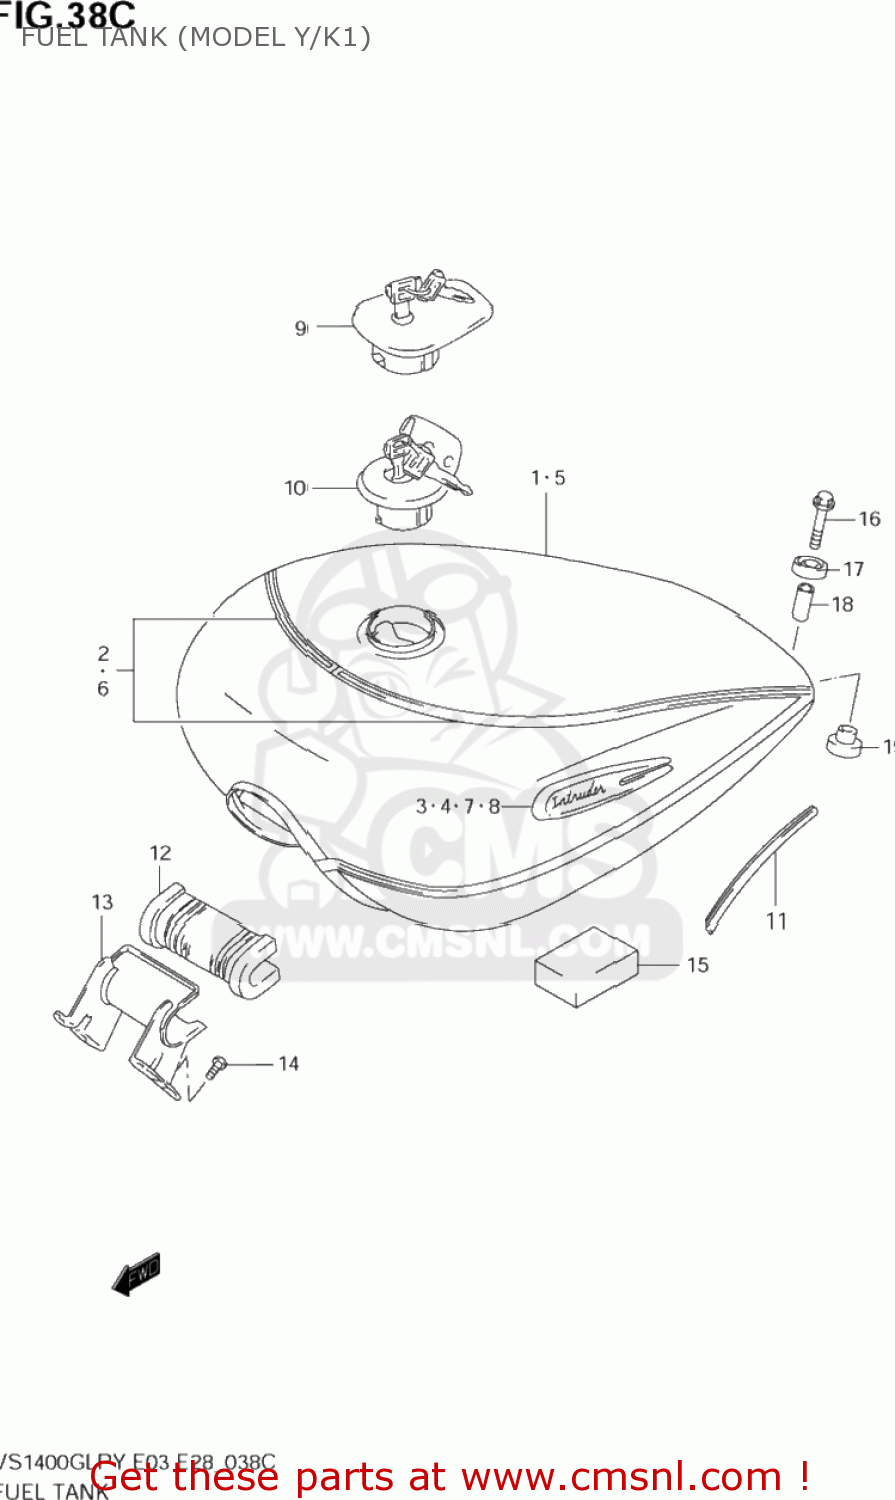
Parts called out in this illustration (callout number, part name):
1	TANK ASSEMBLY,FUEL
2	TAPE SET,FUEL TANK STRIPE
3	EMBLEM,FUEL TANK,R
4	EMBLEM,FUEL TANK,L
5	TANK ASSY,FUEL
6	TAPE SET,FUEL TANK
7	EMBLEM,FUEL TANK,R
8	EMBLEM,FUEL TANK,L
9	CAP SET,FUEL TANK
10	CAP SET,FUEL TANK
11	MOLDING
12	CUSHION,FUEL TANK FR
13	BRACKET,TANK
14	SCREW
15	CUSHION
16	BOLT
17	CUSHION
18	SPACER(6.5X9X22.5)
19	CUSHION
